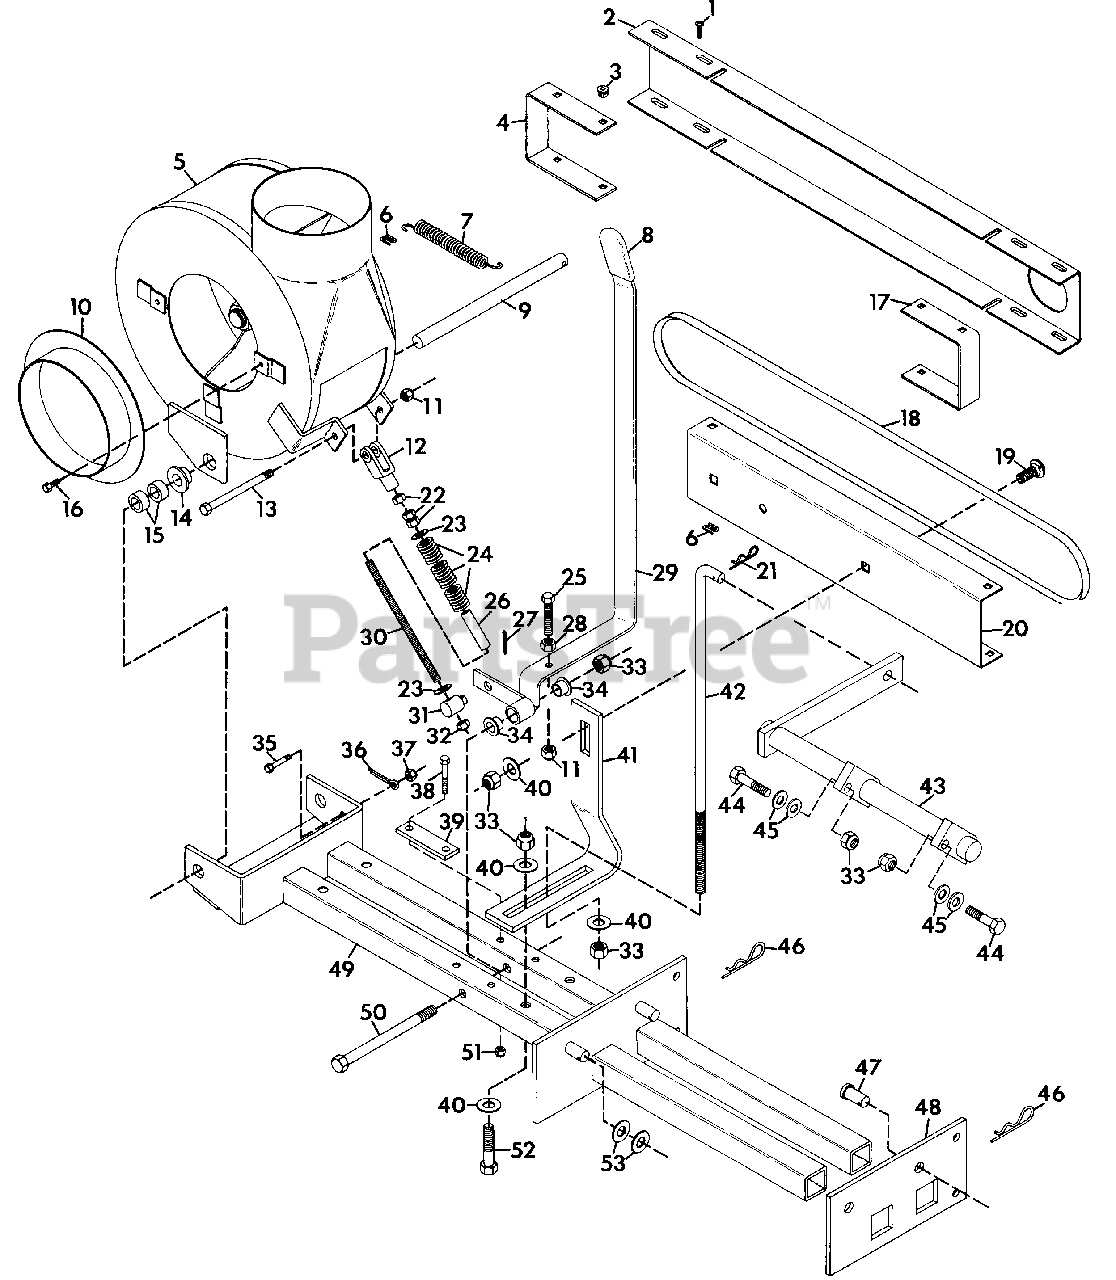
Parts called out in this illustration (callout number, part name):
1	SCREW, MACHINE 1/4-20X.5
2	COVER, BELT
3	GROMMET, PLASTIC
4	GUIDE, RIGHT HAND
5	BLOWER
6	CLIP, SPRING
7	SPRING, EXT. 5.5X.5X20 RATE
8	GRIP, HANDLE
9	ROD, BLOWER PIVOT
10	ADAPTER, HOSE
11	NUT, LOCK 3/8-16
12	CLEVIS, 3/8-24 ADJUSTABLE
13	BOLT, HEX 3/8-16X4.5
14	BUSHING, NYLON .76X1X.6 FLG.
15	SPACER, .760X1.00X.540
16	BOLT, HEX 5/16-18X.75
17	GUIDE, LEFT HAND
18	BELT
19	BOLT, CARRIAGE 1/2-13X1.25
20	CHANNEL, GUARD
21	PIN, COTTER HAIR
22	NUT, HEX 3/8-24
23	WASHER, FLAT .406X.812X.065
24	SPRING, COMP. 1X.78X338 LB/IN
25	BOLT, HEX 3/8-16X2.00
26	SLEEVE, SPRING
27	PIN, COTTER .125X1.00
28	NUT, JAM 3/8-16
29	WELDMENT, HANDLE
30	ROD, ACTUATOR
31	TRUNNION
32	NUT, LOCK 3/8-24
33	NUT, LOCK 1/2-13
34	BUSHING
35	BOLT, HEX 1/4-20X.75
36	PIN, COTTER .25X2.00
37	NUT, LOCK 1/4-20
38	BOLT, HEX 5/16-18X2.00
39	TAB, WEAR
40	WASHER, FLAT 1.38X.56 HARD
41	BRACKET
42	ROD
43	WELDMENT, VAC SUPPORT
44	BOLT, HEX 1/2-13X2.00
45	WASHER, FLAT .531X1.000X.063
46	PIN, HAIR
47	PIN, CLEVIS 5/8X1.125
48	PLATE
49	WELDMENT, BLOWER FRAME
50	BOLT, HEX 1/2-13X5.50
51	NUT, LOCK 5/16-18
52	BOLT, HEX 1/2-13X2.75
53	WASHER, FLAT .656X1.312X.095
NS	DECAL, GRAVELY LOGO
NS	DECAL, PTO
